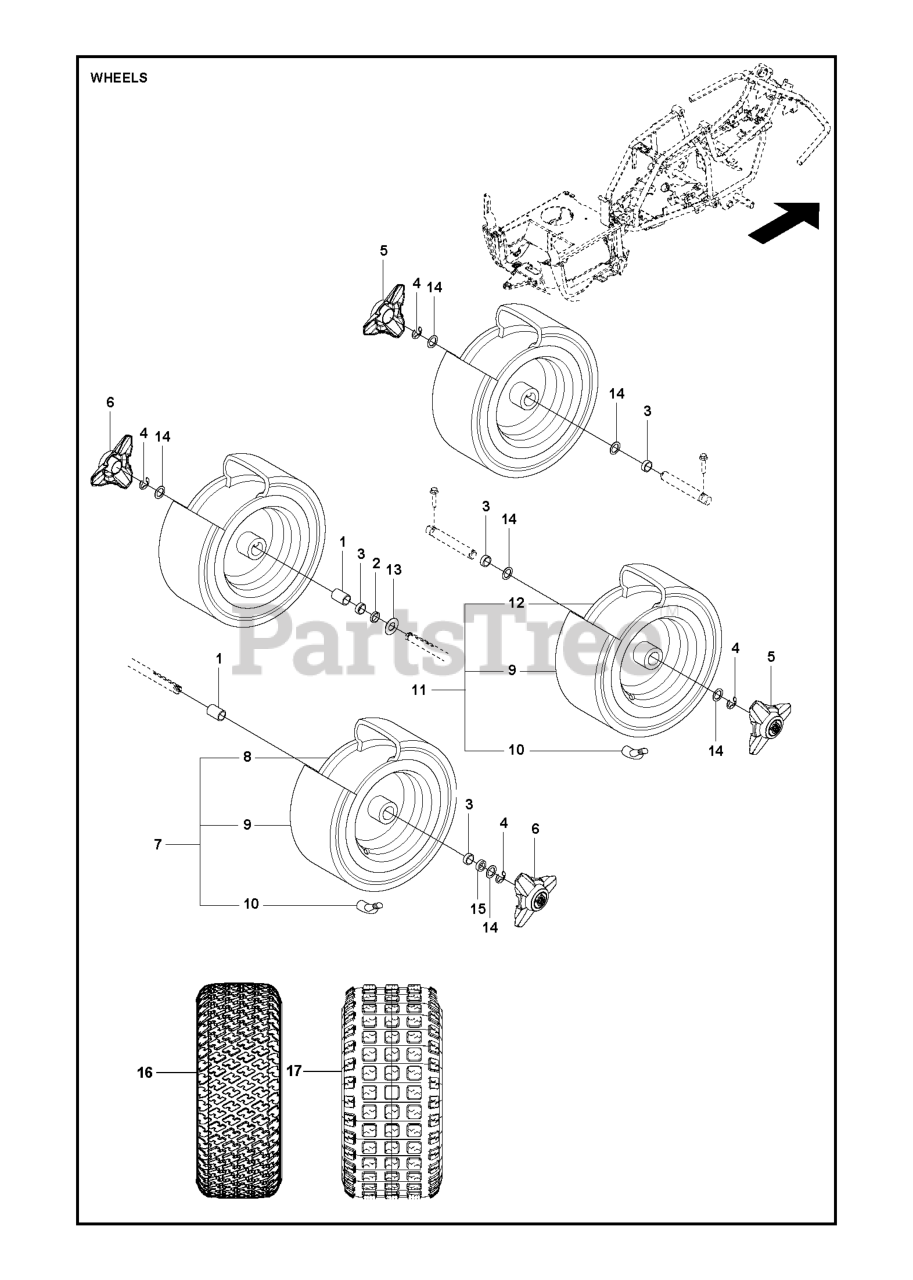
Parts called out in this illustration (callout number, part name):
4	RETAINING RING
7	WHEEL
8	RIM
11	WHEEL
12	RIM
16	TIRE
